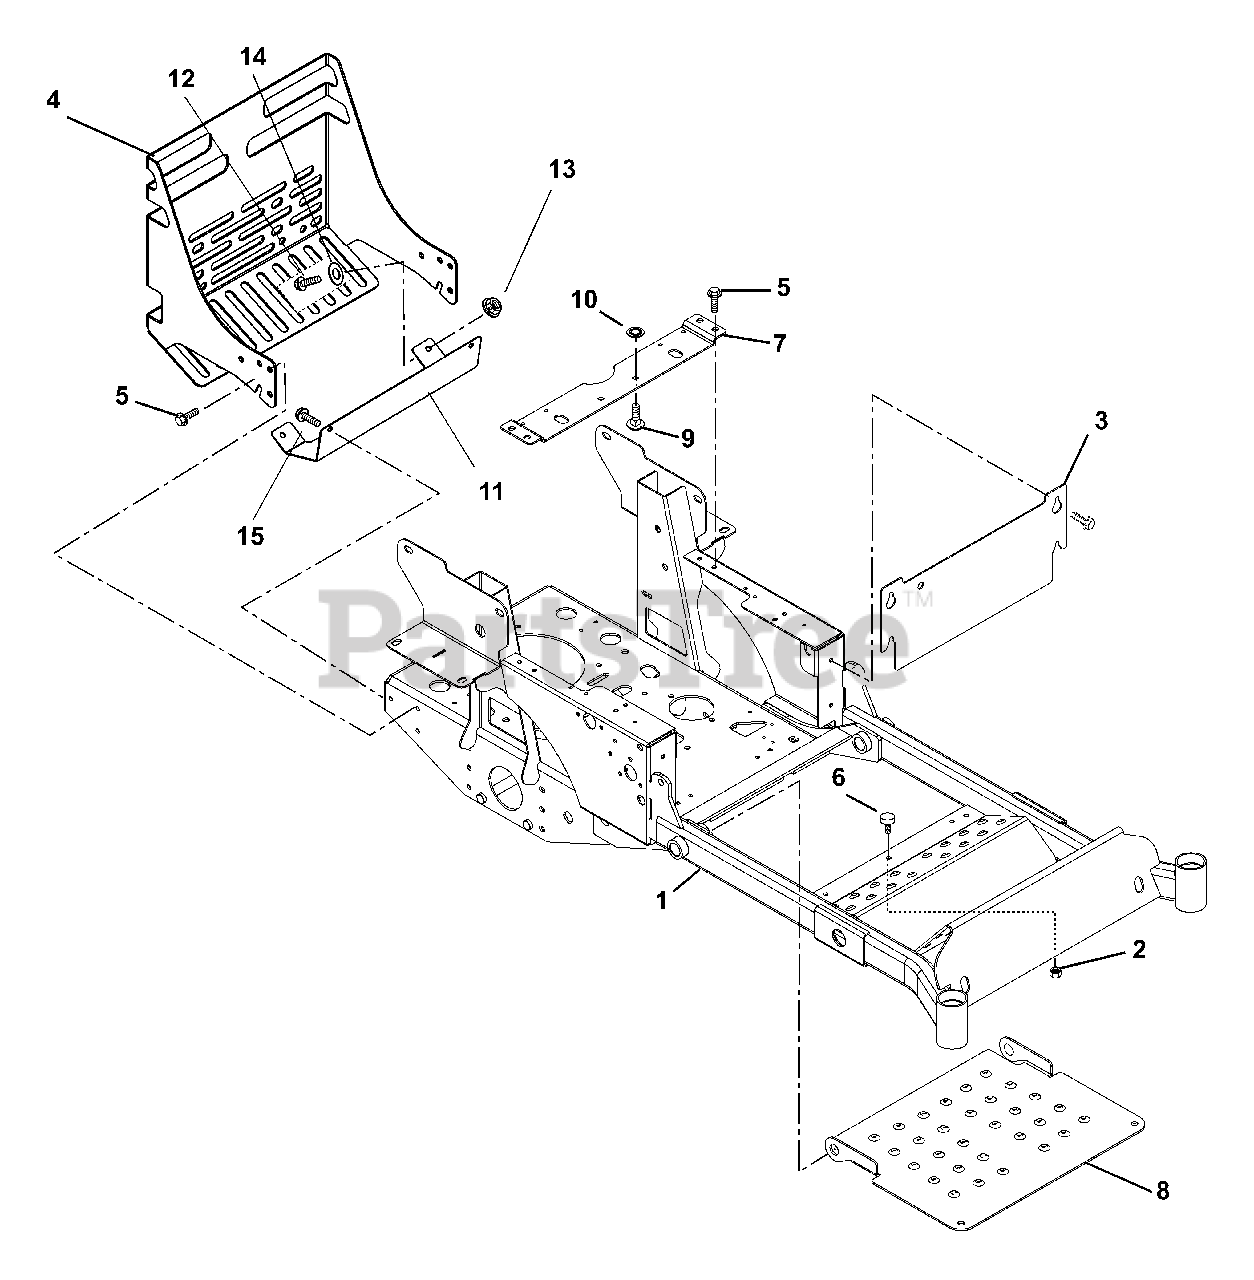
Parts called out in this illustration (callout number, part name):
1	Frame, Compact-Z
2	Nut, Spin Lock Flange .312-18
3	Access Panel
4	Bumper, Rear
5	Screw, Tapping .38-16 x .75 Hex Washer Head
6	Bumper, Rubber
7	Seat Support
8	Panel, Inspection
9	Bolt, Round Head Square Short Neck .31-18 x .75 Grade 5
10	Nut, Push .312
11	Heat Shield, Compact Z
12	Bolt, Hex .38-16 x .75 Grade 5
13	Nut, Nyloc Flange .38-16
14	Washer, Flat Steel .438 x 1.00 x .083
15	Screw, Tapping .38-16 x .50 Hex Washer Head
